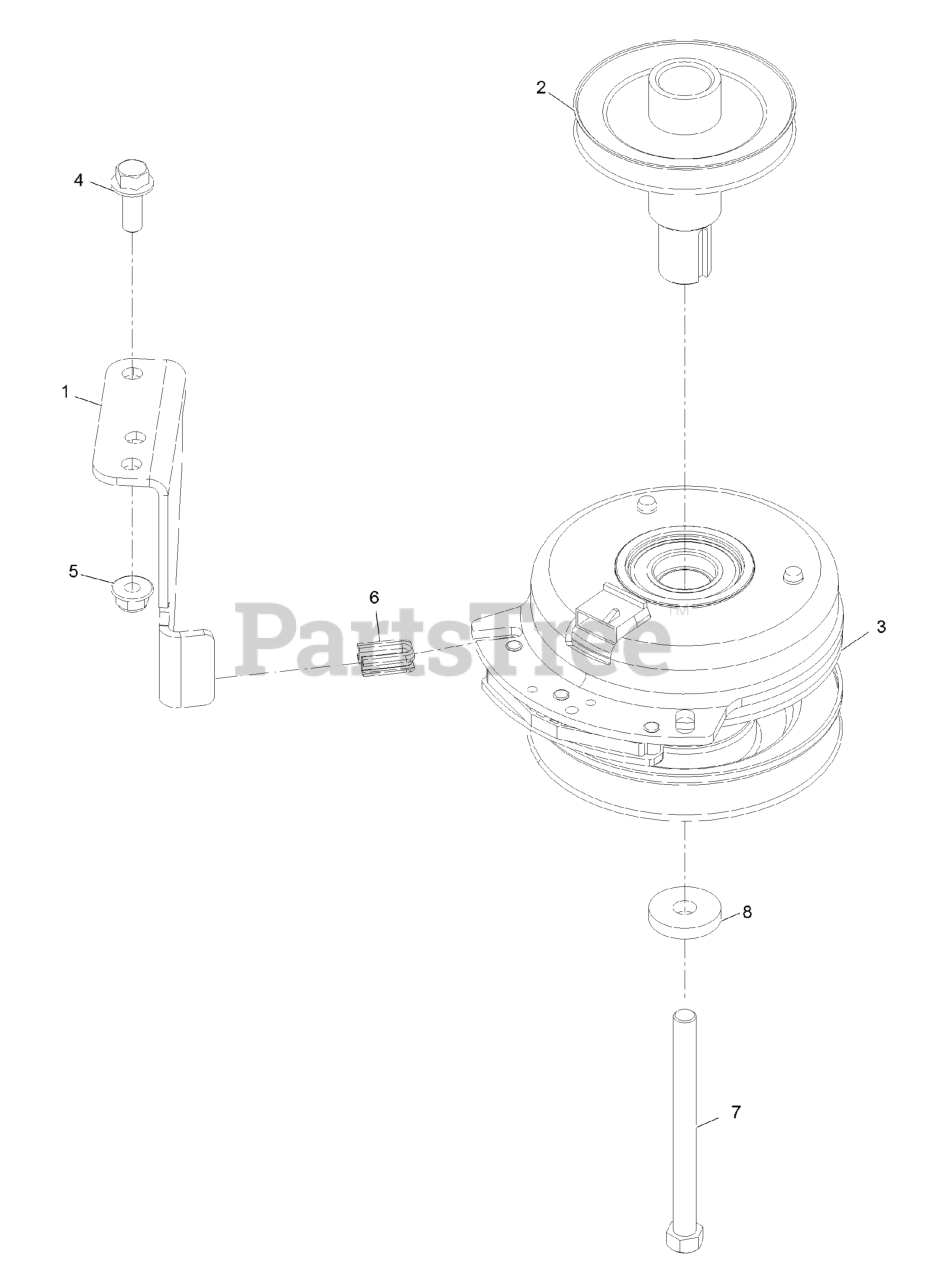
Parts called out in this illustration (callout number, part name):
1	STOP-CLUTCH (WIDE)
2	Pulley-Engine
3	CLUTCH-PTO
4	SCREW-HHF 3/8-16 X 1
5	NUT-HF, NI
6	ISOLATOR-CLUTCH
7	SCREW-HH
8	WASHER
